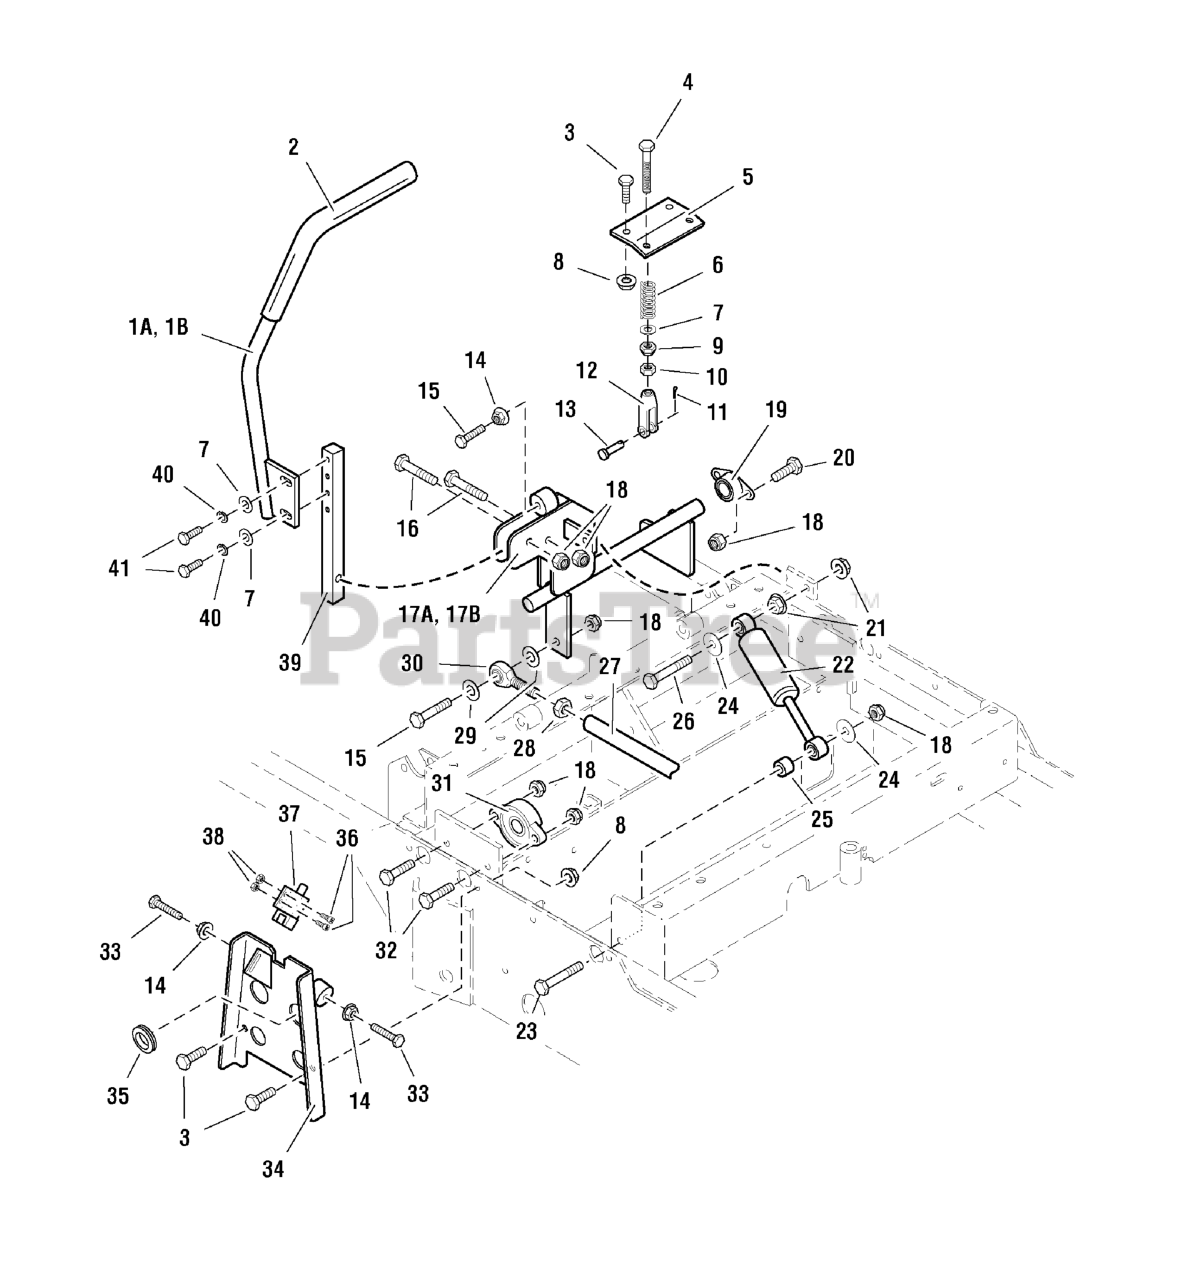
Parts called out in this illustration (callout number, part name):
1A	CONTROL HANDLE - LH
2	GRIP, Foam
3	BOLT, 5/16-18 X 3/4 GD5
4	REVERSE RETURN BOLT
5	NEUTRAL RETURN PLATE
6	SPRING, Compression
7	WASHER, 5/16" SAE
8	NUT, 5/16-18 HEX SERRATED FLANGE (LARGE)
9	NUT, 5/16-24 HEX NYLON LOCK
10	NUT, 5/16-24 Hex
11	HAIRPIN CLIP
12	CLEVIS, 5/16-24, Plastic
13	CLEVIS PIN, 5/16 x 1
14	NUT, 5/16-18 HEX SERRATED FLANGE (SMALL)
15	BOLT, 5/16-18 X 1-1/4 GD5 TFL, CZ
16	BOLT, 3/8-16 X 1-3/4" GD5 CZ
17A	MOTION CONTROL SHAFT - LH
18	NUT, 3/8-16 HEX NYLON LOCK
19	BEARING, Flange
20	BOLT, 3/8-16 X 1" GD5 CZ
21	NUT, 3/8-16 Hex Serrated Flange
22	KIT, SHOCK W/OUT COIL
23	BOLT, 3/8-16 X 2-1/2" GD5 CZ
24	WASHER, 3/8" Fender
25	SPACER, .39 X .75 X .50, CZ
26	BOLT, 3/8-16 X 2-1/4" GD5 CZ
27	CONTROL ROD
28	NUT, 3/8-24 Hex
29	WASHER, 3/8 SAE
30	BALL JOINT, 3/8-24 Male
31	BEARING, Flange
32	BOLT, 3/8-16 X 1-1/4" GD5 CZ
33	BOLT, 5/16-18 x 2 TFL
34	NEUTRAL LOCK PLATE
35	GROMMET, 7/8"
36	SCREW, #10-24 X 1 RS, CZ
37	SWITCH (see electrical group)
38	NUT, #10-24 Hex
39	MOUNT, CONTROL ARM - BLK
40	WASHER, 5/16 LOCK CZ
41	BOLT, 5/16-18 X 3/4 GD5
